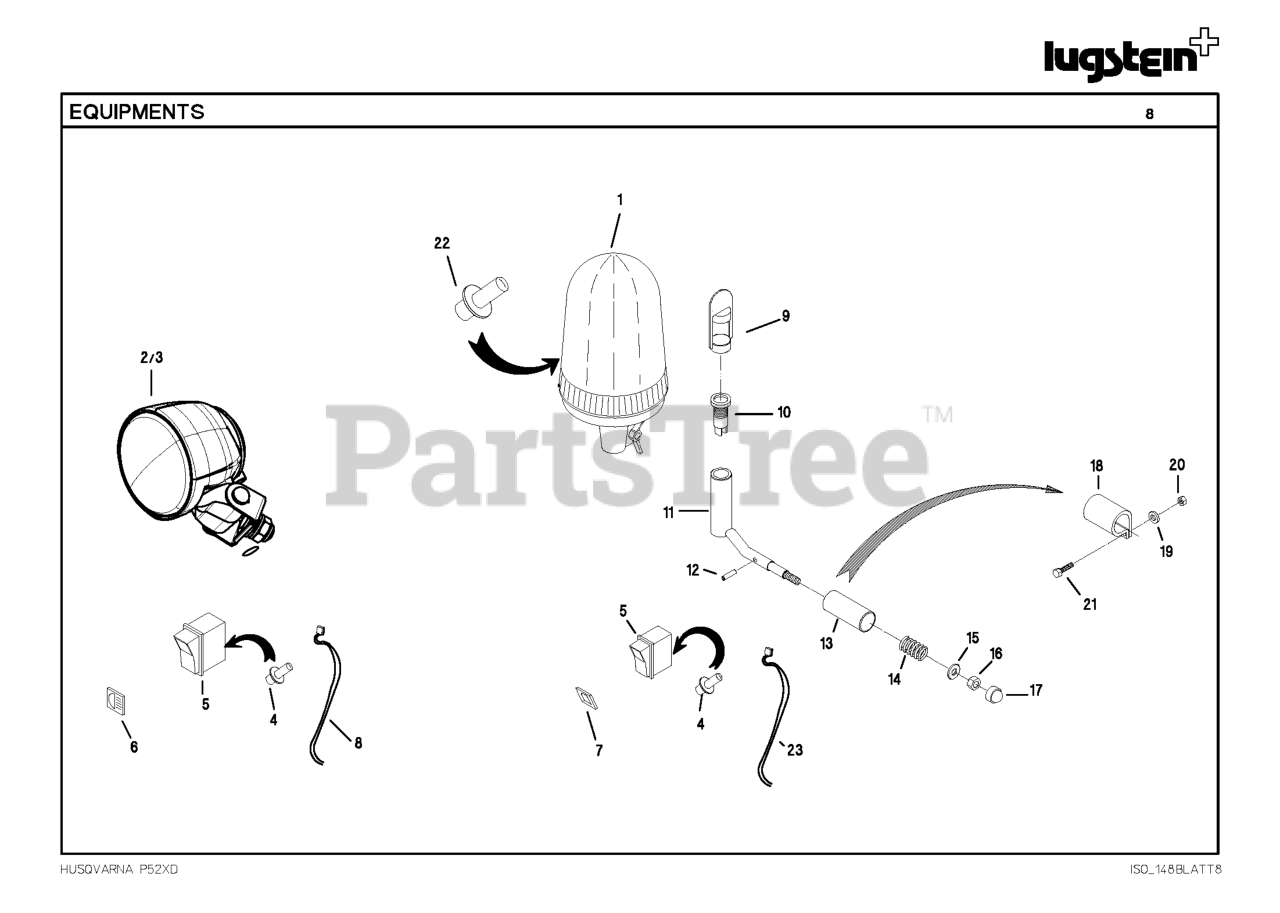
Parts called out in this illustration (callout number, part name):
15	WASHER BRB 8.4X17
16	LOCKNUT M8
17	PROTECTIVE COVER
20	LOCKNUT M5
